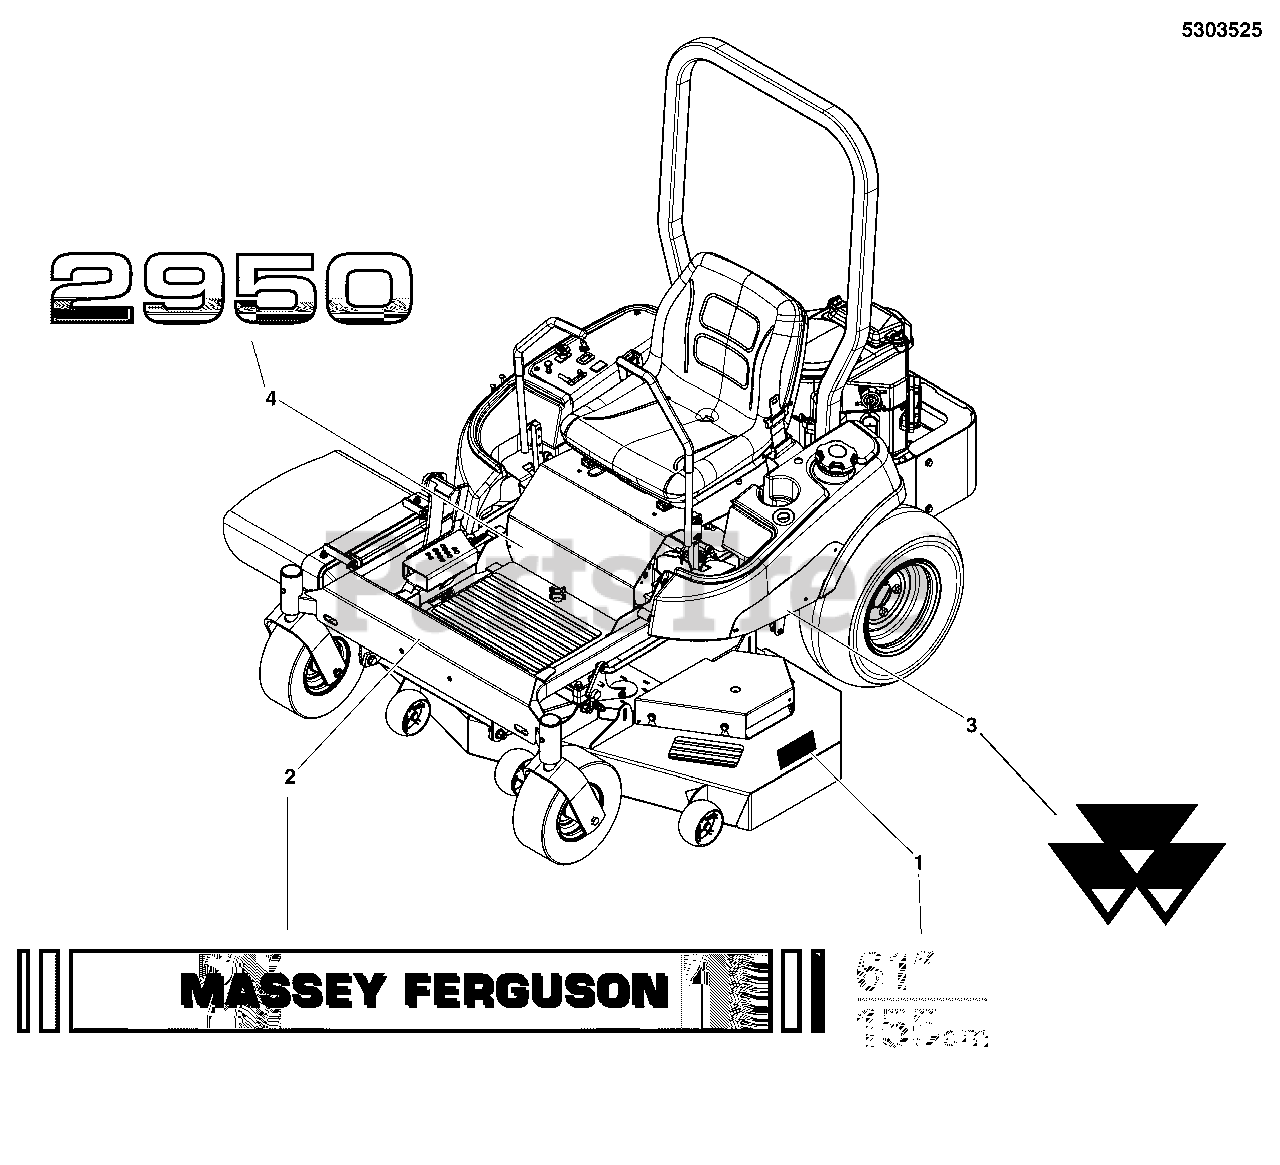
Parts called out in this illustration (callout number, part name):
1	DECAL, MOWER WIDTH 61IN/155CM
2	DECAL, MASSEY, FRONT, 3900
3	DECAL, MASSEY LOGO SIDE PANEL
4	DECAL, MF MODEL 2950
